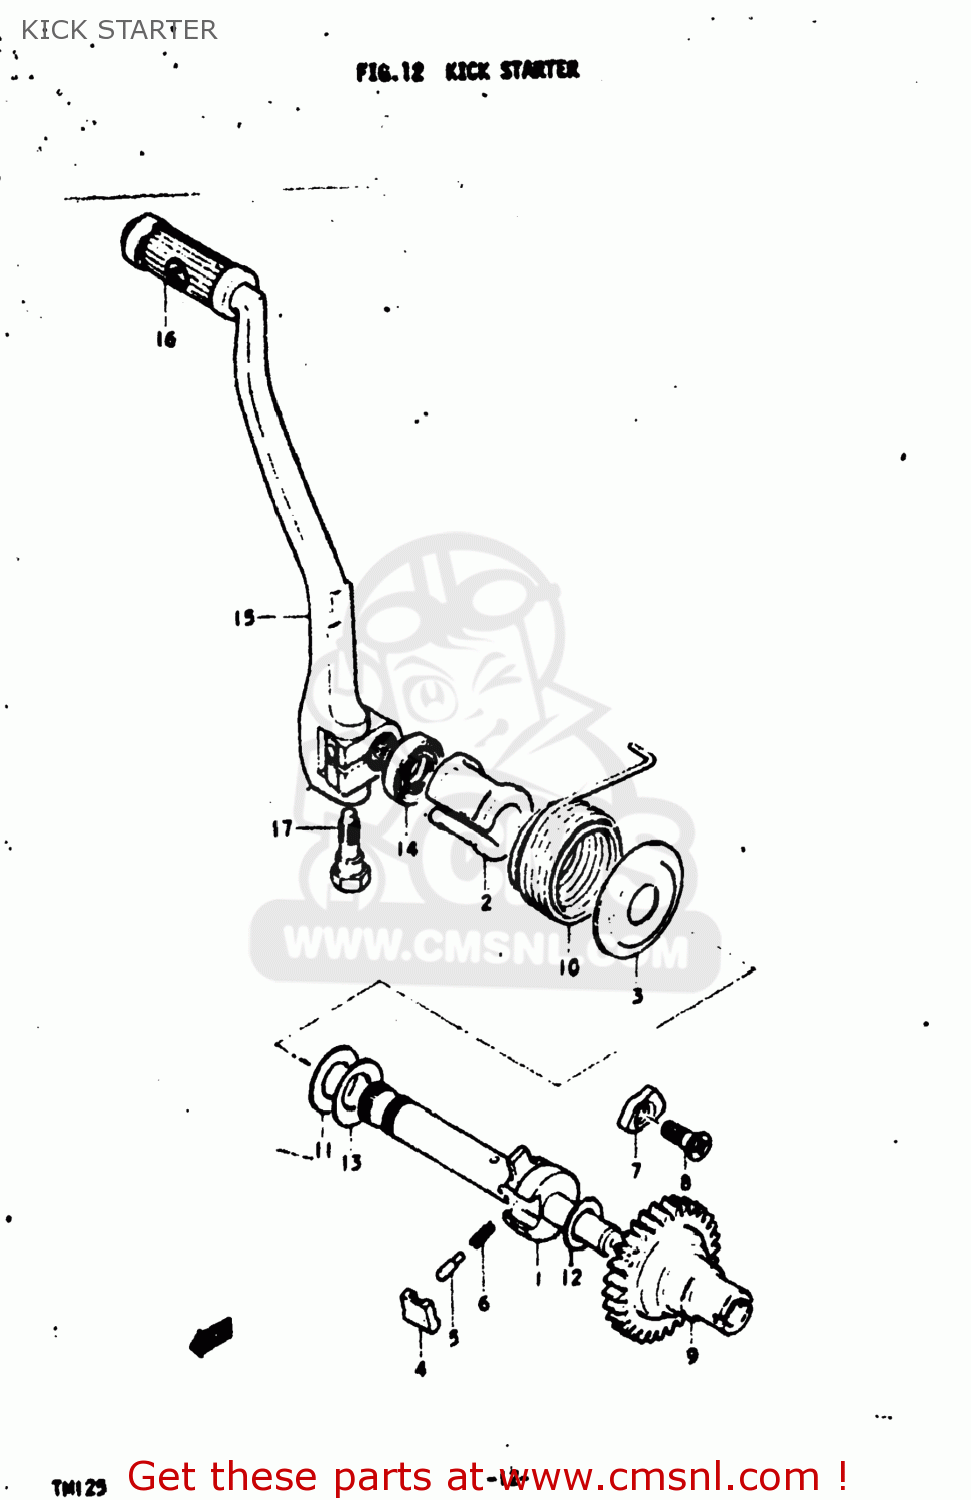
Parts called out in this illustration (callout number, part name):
1	SHAFT,KICK STARTER
2	GUIDE,KICK STARTER SFT SPRING
3	HOLDER,KICK STARTER SHAFT SPR
4	PAWL,KICK STARTER
5	PIN(5X15.5)
6	SPRING
7	LIFTER,KICK STARTER PAWL
8	SCREW(6X19)
9	GEAR,KICK STARTER DRIVE
10	SPRING
11	WASHER(16X30X0.5)
12	WASHER
13	WASHER
14	SEAL,OIL(16X30X8)
15	LEVER ASSEMBLY,KICK STARTER
16	RUBBER,KICK STARTER PEDAL
17	BOLT
